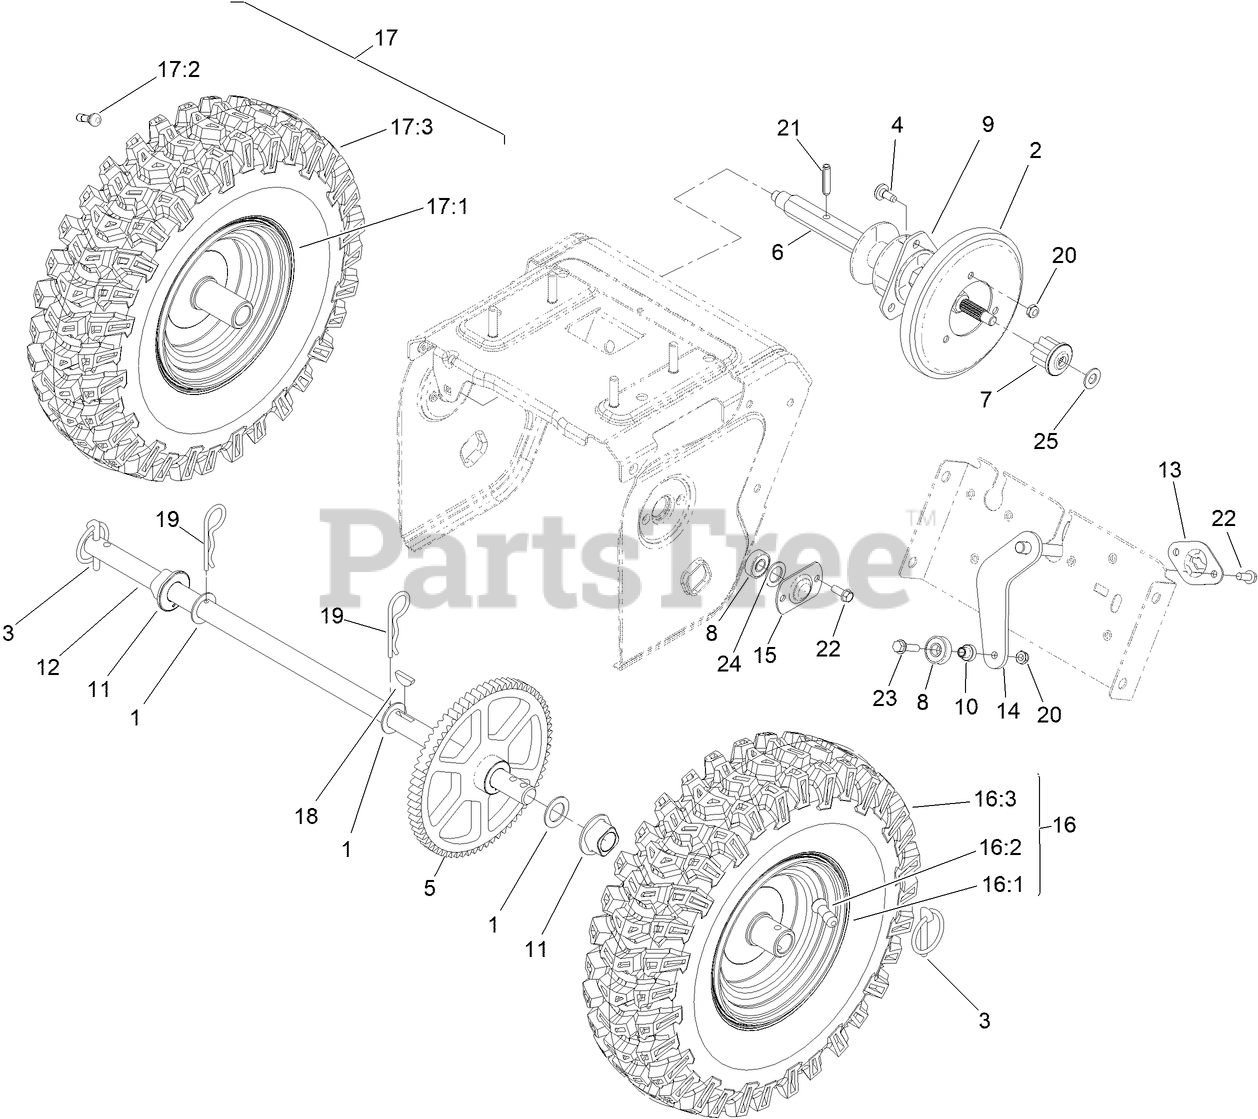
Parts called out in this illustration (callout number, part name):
1	WASHER-THRUST
2	WHEEL-FRICTION
3	KLIK PIN ASM
4	SCREW-SHOULDER
5	GEAR-AXLE
6	SHAFT-HEX
7	GEAR-PINION, 8 TOOTH
8	BEARING-BALL
9	TRUNNION
10	SPACER-PLATE, SHIFT
11	BUSHING-AXLE
13	RETAINER-PLATE, SHIFT
14	SHIFT PLATE ASM
15	RETAINER-BEARING
16	WHEEL AND TIRE ASM, LH (15X4)
16:1	WHEEL (15X4 TIRE)
17	WHEEL AND TIRE ASM, RH (15X4)
17:1	WHEEL (15X4 TIRE)
18	KEY-WOODRUFF
19	PIN-HAIR
20	NUT-LOCK, NI
21	PIN-ROLL, SLOTTED
22	SCREW-HWH
23	SCREW-HWHTF
24	WASHER-RUBBER
25	WASHER-FLAT
